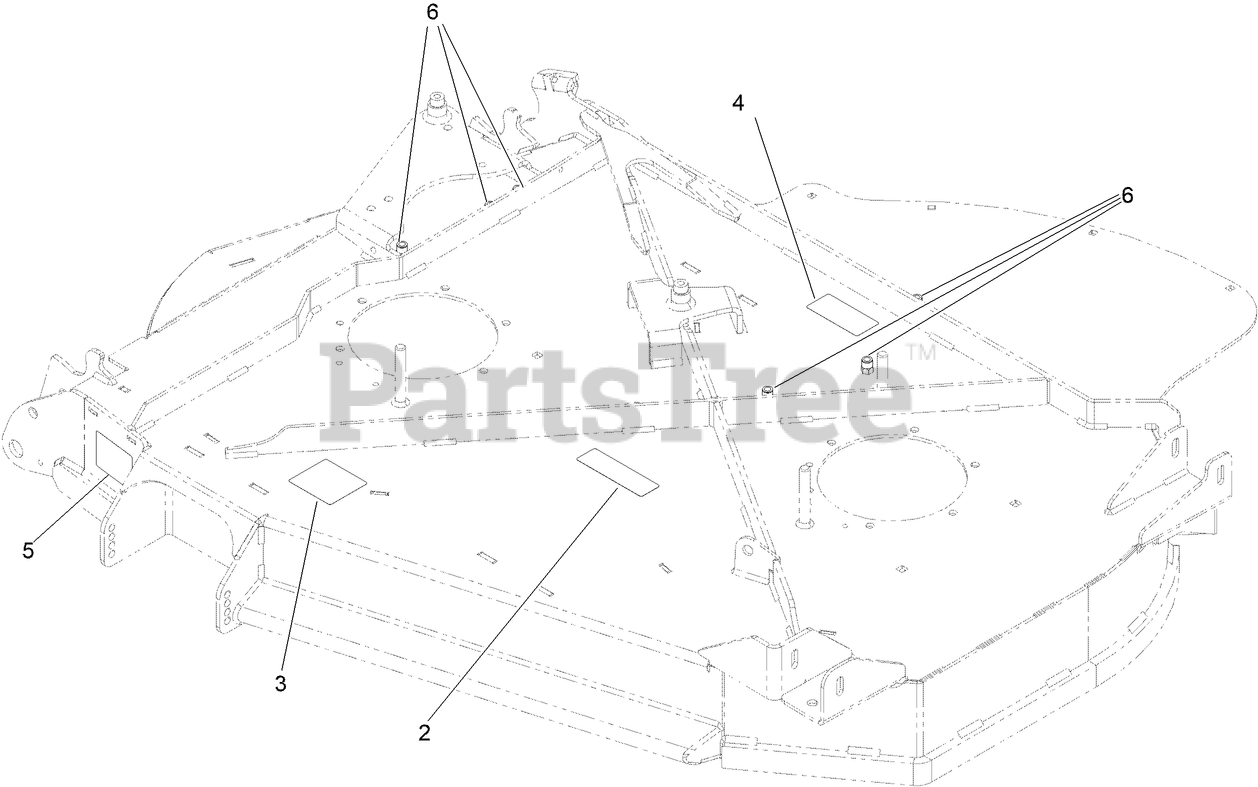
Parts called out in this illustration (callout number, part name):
2	DECAL-COVER, MISSING
3	DECAL-DANGER, THROWN OBJECT
4	DECAL-BOLT TORQUE
5	DECAL-WARNING, PINCH POINT
6	NUT-CLINCH,HEX
